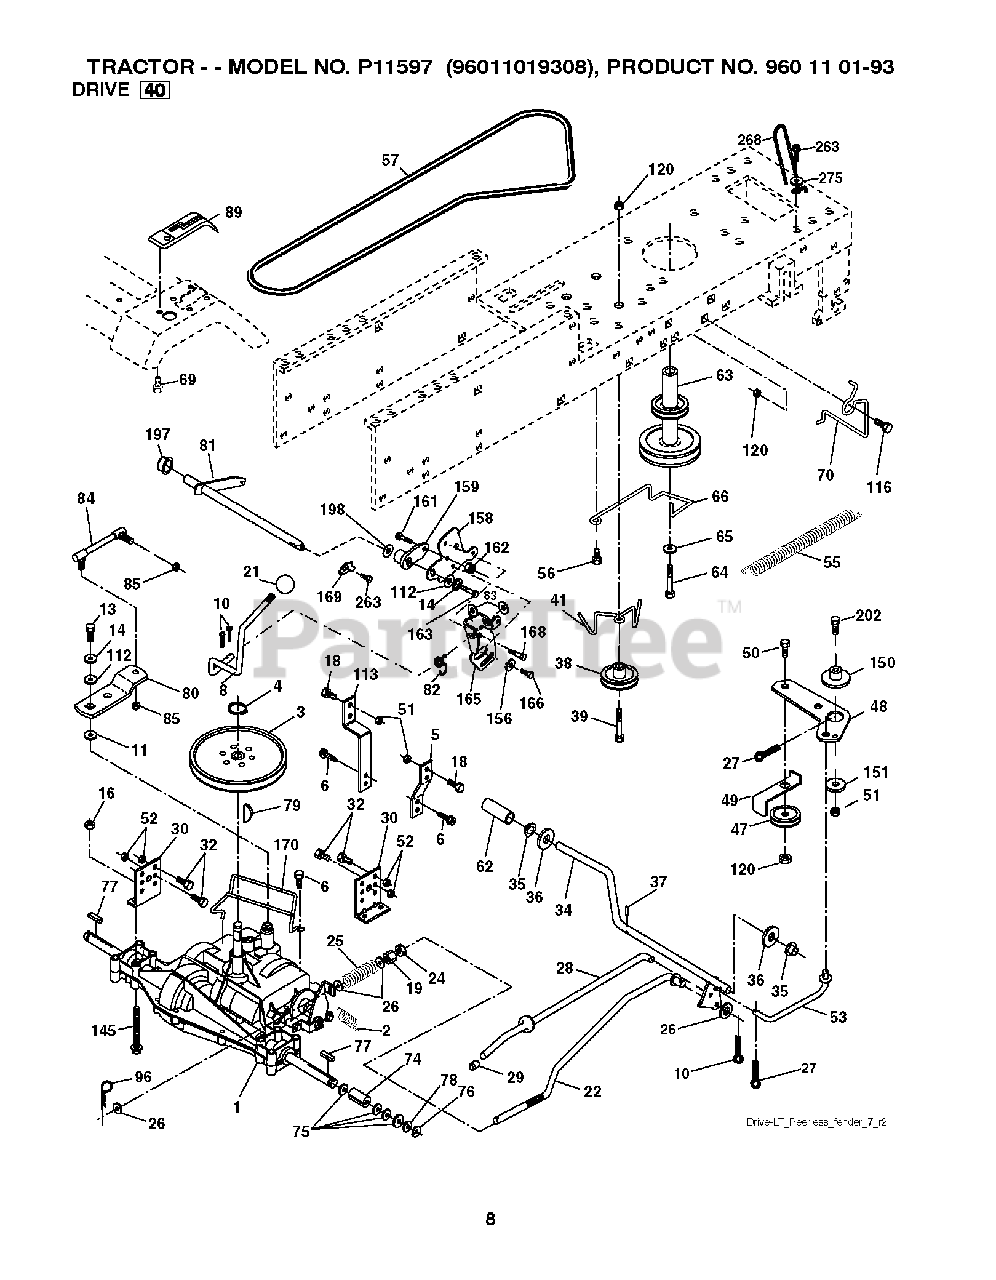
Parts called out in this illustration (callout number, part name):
2	SPRING,BRAKE RETURN
4	RETAINING RING LT
6	SCREW 5/16"
8	ROD SHIFT FENDER ADJUST LT
10	PIN COTTER
11	WASH-SHFT PLT LT
13	BOLT 1/4-28X3/4
14	LOCKWASHER
16	NUT.71038.31-18.HEX.NYLOCK
18	BOLT
19	NUT
21	KNOB T (1/2-HOLE)
24	NUT
25	SPRING ROD LT
27	COTTER PIN
28	ROD, PARKING BRAKE
30	BRKT, MOUNT TRNSAXLE
32	BOLT
34	SHAFT, FOOT PEDAL
35	BEARING.NYLON
36	WASHER LT
37	DRIVE PIN
38	PULLEY IDLER COMPOSITE
41	KEEPER, BELT IDLER
47	IDLER PULLEY
48	BELLCRANK, CLUTCH
49	RETAIN BELT
50	BOLT.3/8-16X1.50
51	LOCKNUT
52	LOCKNUT
53	LINK.CLUTCH.7.66.2005
55	SPRING, RETURN LT
57	BELT, V GROUND DRIVE 95 25
62	PEDAL COVER T
63	ENGINE PULLEY
64	BOLT HEX 7/16-20X4-1/4"
65	LOCKWASHER
66	KEEPER BELT ENGINE
69	SCREW.HI-LO.CONSOLE
70	KEEPER BELT ENG
81	SHAFT ASM CROSS TAPERED
83	WASHER
84	LINK.TRNSAXLE
85	NUT LOCK CENTER 1/4 -28 FNTHD
89	CONSOLE SHIFT STLT
96	RETAINER M
112	WASHER LT
113	STRAP TORQUE LH LT
116	BOLT D
120	NUT LOCK FLG 3/8-16 UNC
145	BOLT
150	SPACER, RETAINER
151	WASHER 12/32X2X10GA
156	WASHER.SRRTD.5/16
158	BRACKET
159	HUB.SHIFT
161	BOLT
162	NUT.CROWNLOCK.1/4
163	BOLT
165	RP BRACKET
166	SCREW
168	BOLT.SHOULDER.5/16-18X
169	PLATE FASTENING LT
170	KEEPER BELT T/A
197	NYLINER SNAP 5/8" ID
202	BOLT
263	SCREW, 3/8-16X3/4
275	WASHER
